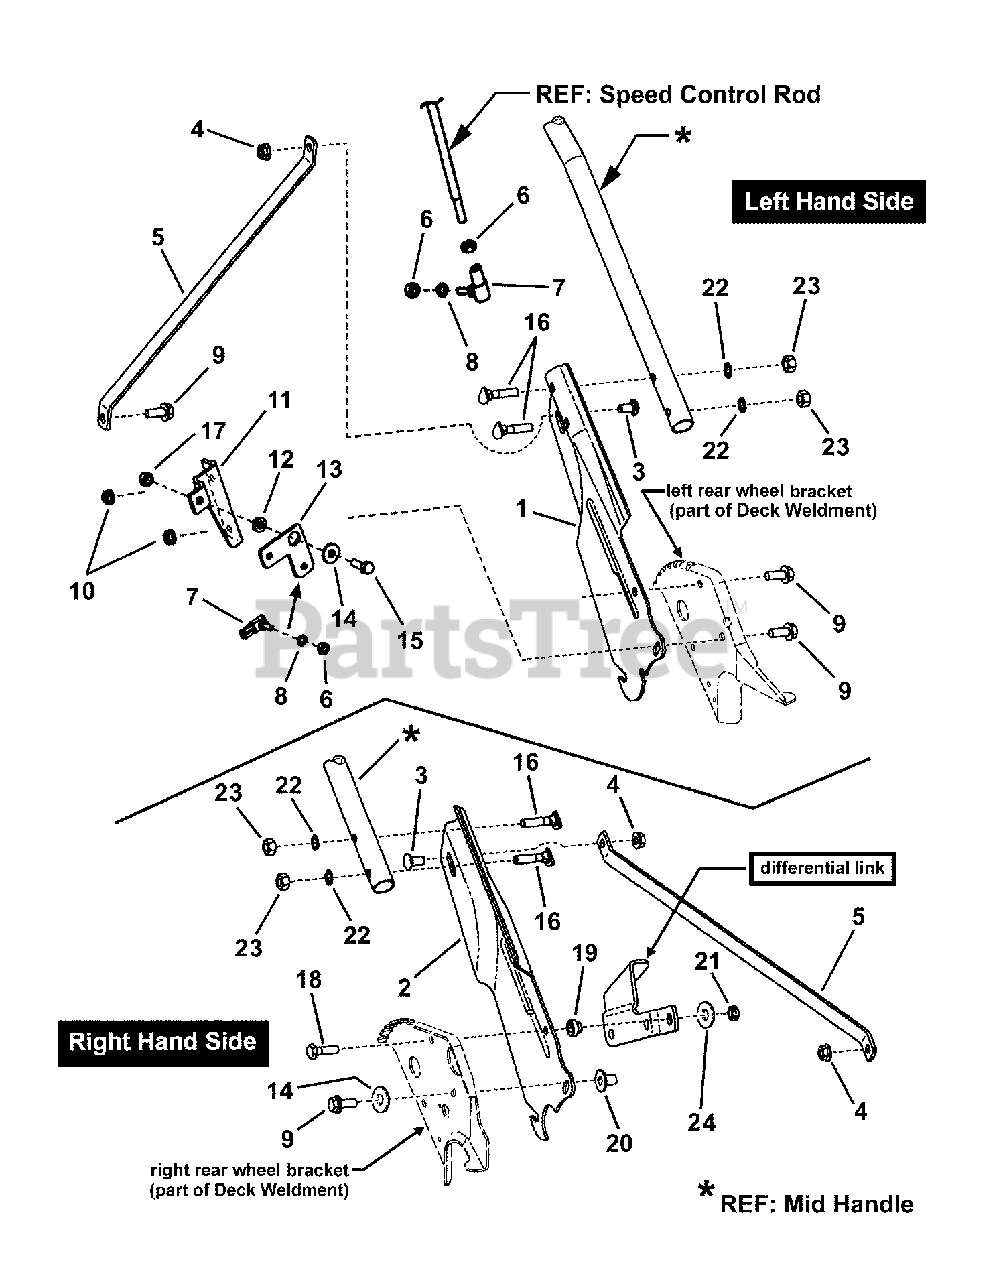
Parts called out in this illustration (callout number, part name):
1	HANDLE, Lower LH (Adjustable)
2	HANDLE, Lower RH (Adjustable)
3	BOLT, 5/16-18 x 5/8" Short Neck Carriage GR 5
4	NUT, 5/16-18 Hex Flange Lock GR 5
5	STRAP, Handle
6	NUT, 1/4-28 Hex, GR 5
7	BALL JOINT, 1/4-28
8	WASHER, 1/4" Internal Tooth Lock
9	BOLT, 5/16-18 x 3/4" Hex Flange Lock GR 5
10	NUT, 5/16-18 Hex Flange Lock, GR 5
11	BRACKET, Bell Crank
12	SPACER, .33 x .63 x .156
13	BELL CRANK
14	WASHER, .33 x .88 x .09 Flat
15	SCREW, 5/16-18 x 7/8" Hex Head Cap, GR 5
16	BOLT, 5/16-18 x 1-1/2" Curved Head
17	NUT, 5/16-18 Hex Center Lock
18	SCREW, 5/16-24 x 1" Hex Head Cap GR5
19	BUSHING, Differential
20	NUT, 5/16-18 Tee
21	NUT, 5/16-24 Hex Center Lock, GR 5
22	WASHER, 5/16" Internal Tooth Lock
23	NUT, 5/16-18 Hex, GR 5
24	WASHER, 3/8" Flat
